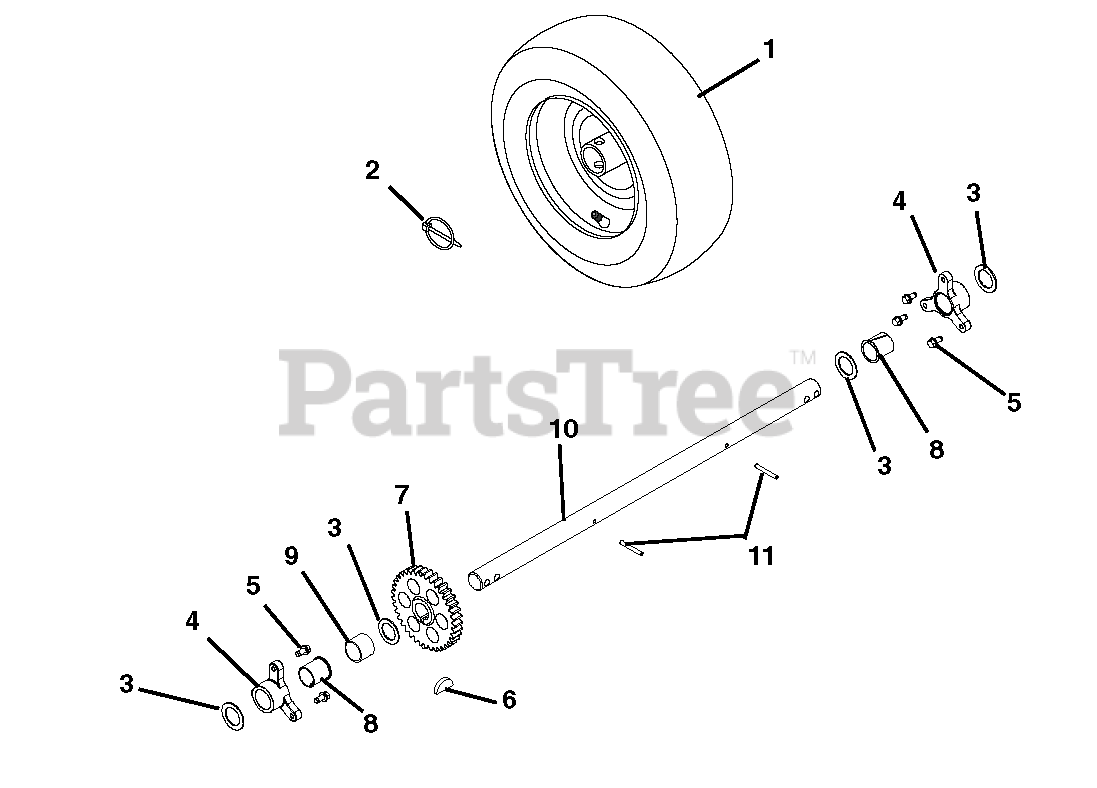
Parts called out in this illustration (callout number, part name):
1	TIRE/WHEEL, RH 15X5.00-6 PIN
1	TIRE/WHEEL, LH 15X5.00-6 PIN
1	TIRE, 15X5.00-6 K478
2	PIN-LOK .31X2.00
3	WSHR-FL-STL 1.010X1.505X.062YZ
4	BUSHING, RAKE SHAFT 1"
5	SCR-TAP .25-20X.50 HWH TR YWZ
6	KEY-WDRF .25X.750X.313 SAE91
7	GEAR, SPUR
8	BSHG-FLG SPLIT NYLINER 1.0" HP
9	BSHG-SLV, 1.012X1.125X1.00
10	AXLE, 1.00" SOLID
11	PIN-ROLL .188X1.25
